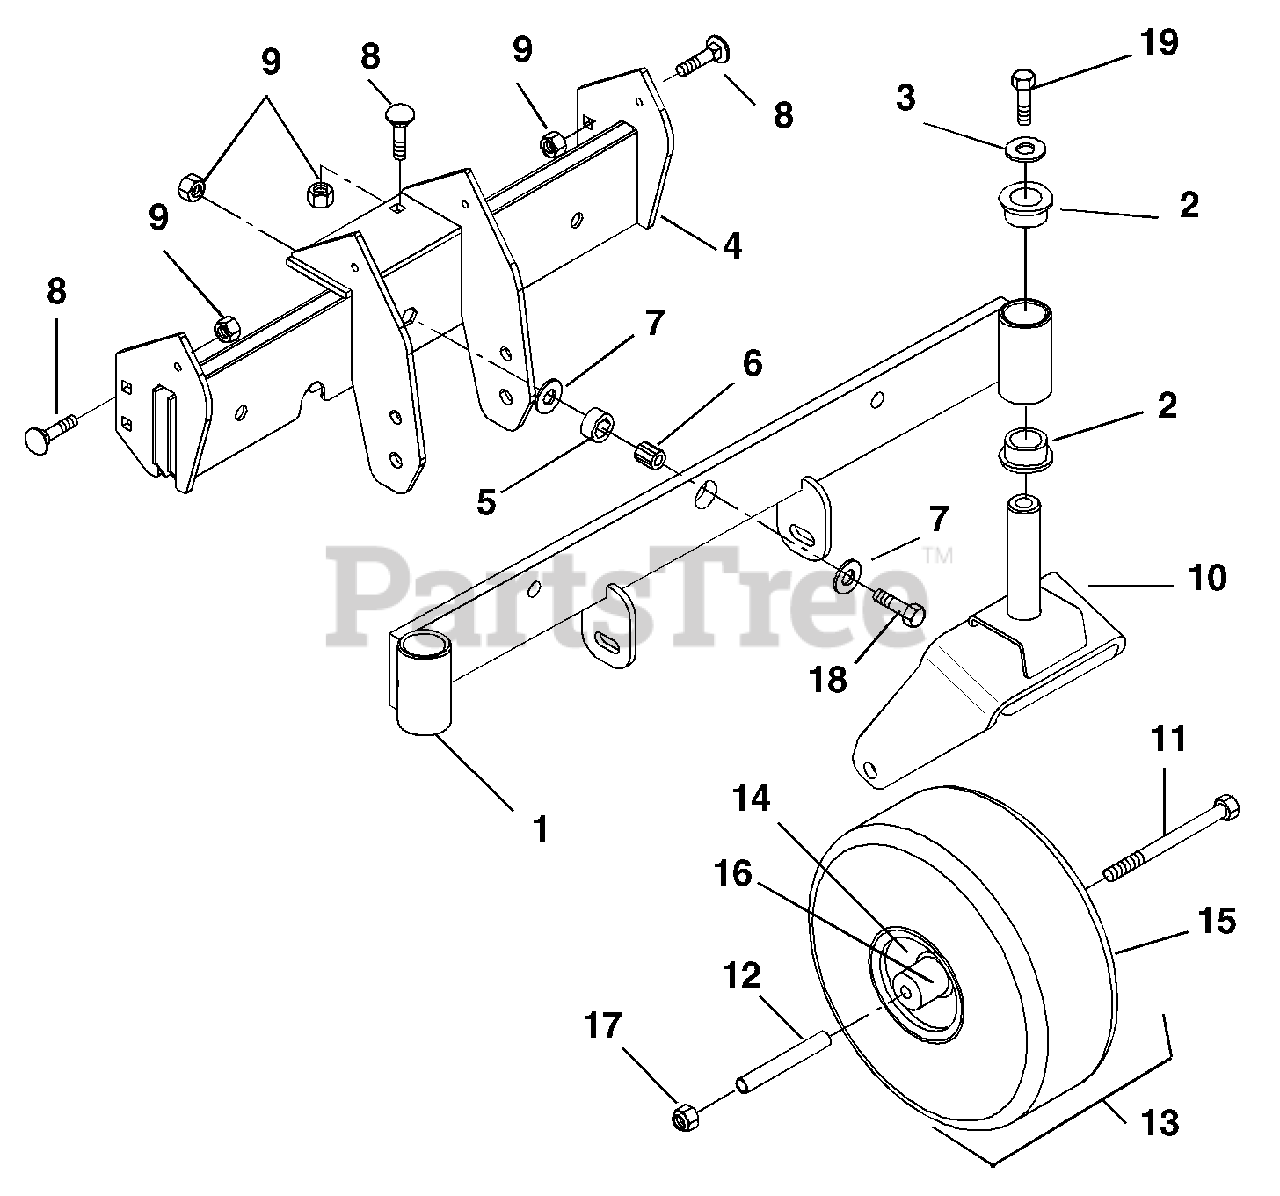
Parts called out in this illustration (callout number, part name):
1	WELDMENT, AXLE - WOODS
2	BSHG-FLG1.020X1.385X.75X1.75NY
3	WSHR-FL-STL .390X1.5X.125 YWZC
4	WELDMENT, AXLE FRAME
5	BSHG-SLV .626X1.000X.524 HEX
6	BSHG-SLV .377X.623X.775 HEX
7	WSHR-FL-STL .375X1.125X.065YWZ
8	@BLT-RDHDSQNK .38-16X.75 G5YZ
9	@NUT-LK-TOP-FLG .38-16 YWZC
10	FORK - CASTER
11	@BLT-HEX .50-13X6.50 GR5 YWZC
12	BUSH.,CASTER FORK
13	T/WHL 11X4.00-5 RIBBED
14	RIM ASSY 11X4.00-5
15	TIRE RIBBED 11X4.00-5
16	RIM BEARING-11X4.00-5 RIM
17	@NUT-LK-CTR .50-13 YWZC
18	@BLT-HEX .38-16X1.50 GR5 YWZC
19	@SCR-TAP .38-16X1.25 HWH TR YZ
